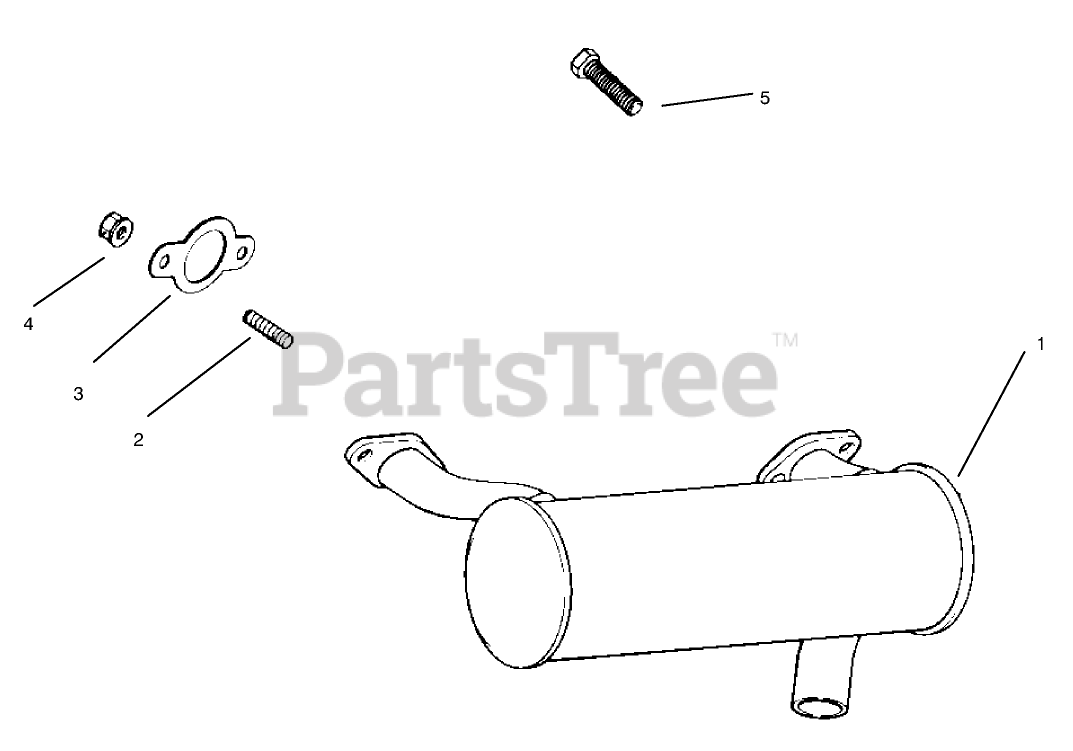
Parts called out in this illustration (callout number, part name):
1	Muffler
2	Stud
3	Gaskt-Exhaust
4	Nut
5	Screw, tank bracket - starter end
